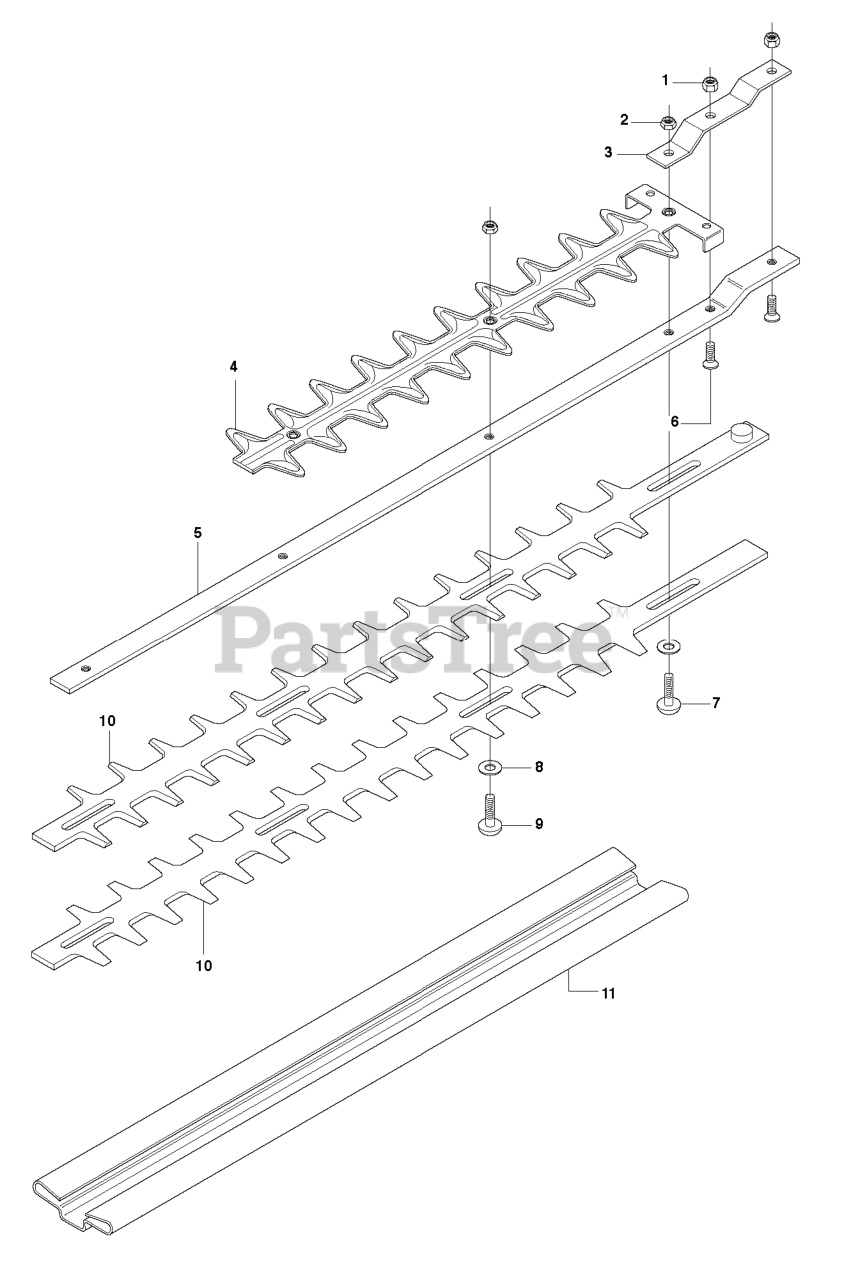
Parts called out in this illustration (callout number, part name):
4	PLATE
5	PLATE
5	GUIDE PLATE
10	BLADE
11	COVER
11	PROTECTOR
